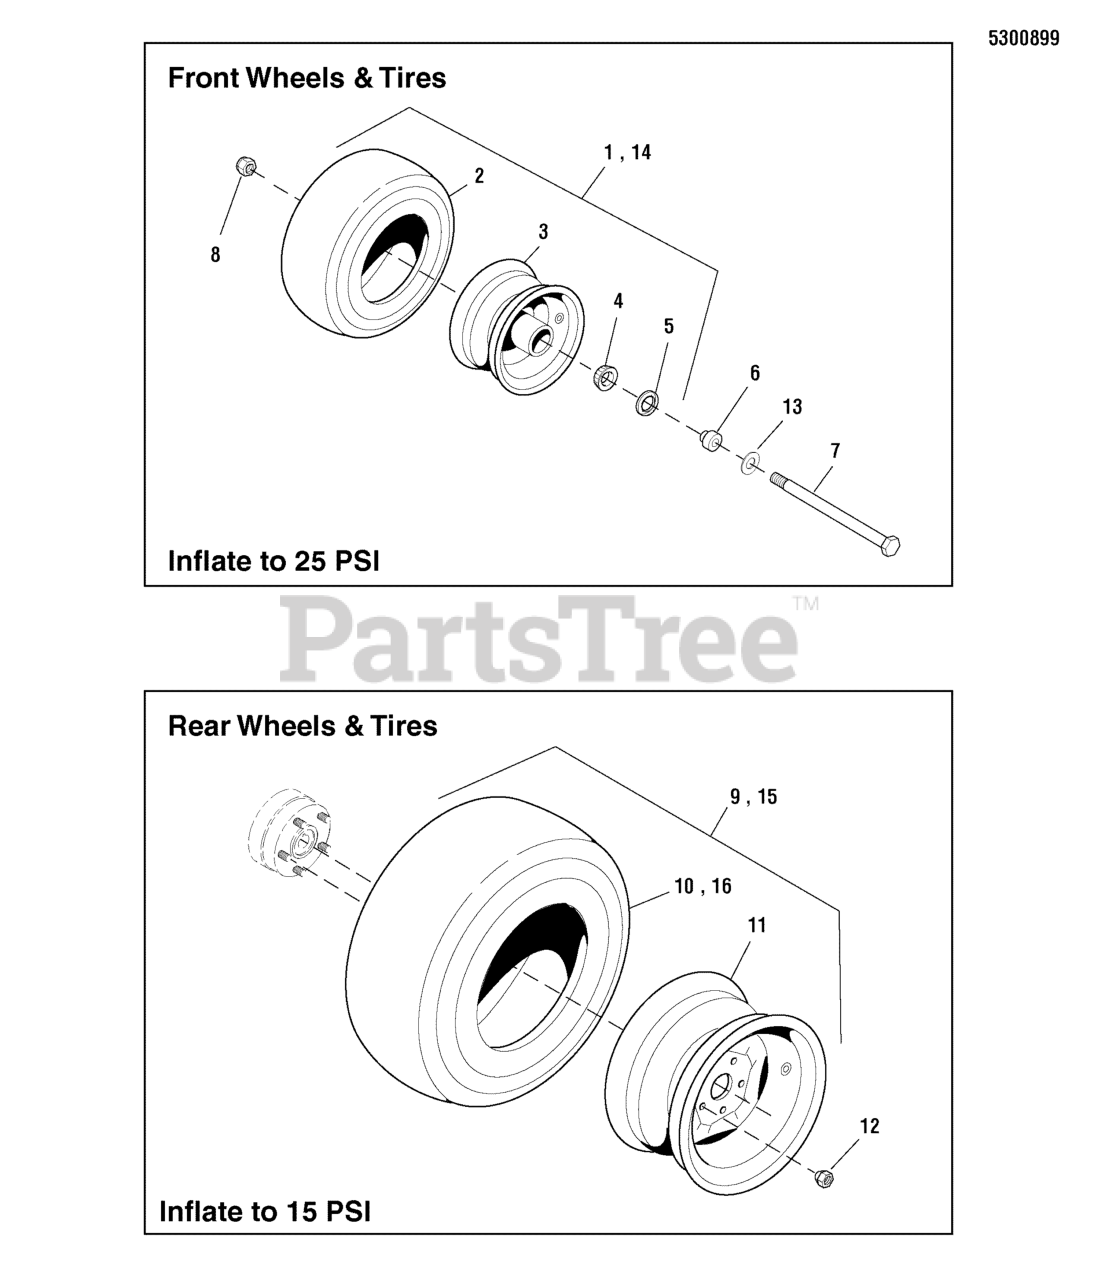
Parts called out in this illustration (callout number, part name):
1	WHEEL & TIRE ASSEMBLY, 13 x 5.0 - 6
2	TIRE, 13 x 5.0 - 6
3	WHEEL ASSEMBLY, for 13 x 5.0 - 6 Tire
4	BEARING, Tapered Roller
5	SEAL, GREASE
6	ADAPTER, CASTER AXLE, CZ
7	BOLT, 1/2-13 x 8"
8	NUT, Hex Flange, Nylock, 1/2-13
9	WHEEL & TIRE ASSEMBLY, 22 x 11 - 10
10	TIRE, 22 X 11.0 - 10 (SV)
11	WHEEL ASSEMBLY, 10 X 7 (SV)
12	LUG NUT, 1/2-20
13	WASHER, 1/2 SAE
14	* FLAT-FREE TIRE ASSEMBLY, 13 x 5.0 - 6
15	WHEEL & TIRE ASSEMBLY, 22 X 10 - 10
16	TIRE, 22 X 10.00 -10
